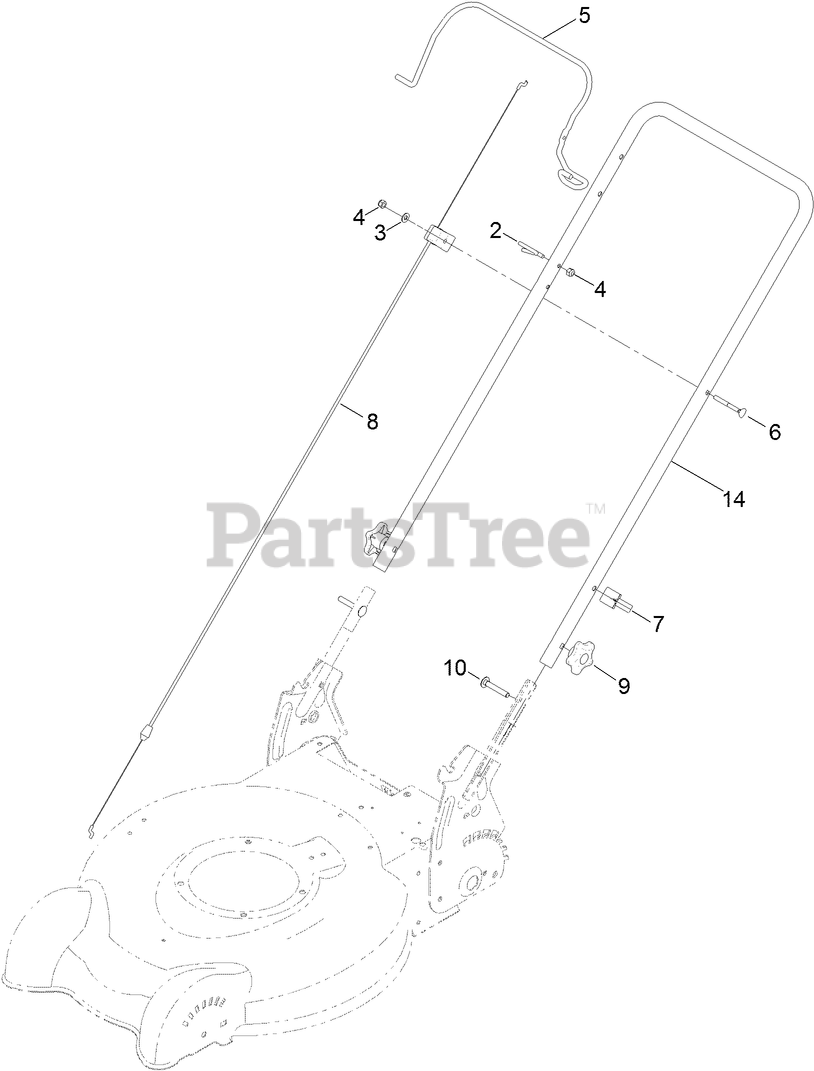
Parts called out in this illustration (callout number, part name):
2	GUIDE-ROPE
3	WASHER-FLAT
4	NUT-LOCK, NI
5	BAIL-BRAKE
6	SCREW-HANDLE
7	GUIDE-CABLE
8	CABLE-BRAKE, ENGINE
9	KNOB-HANDLE
10	BOLT-CARR
